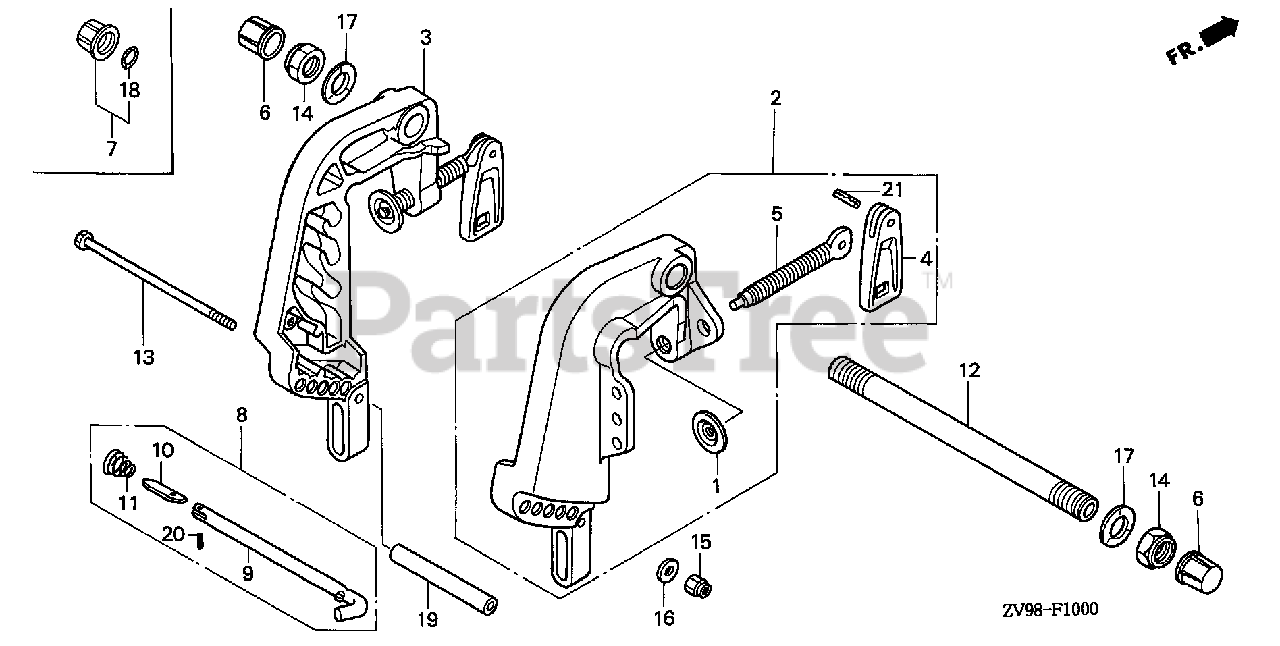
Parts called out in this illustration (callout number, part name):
1	PLATE, PUSH
2	BRACKET, R. STERN *NH282MU* (OYSTER SILVER METALLIC-U)
3	BRACKET, L. STERN *NH282MU* (OYSTER SILVER METALLIC-U)
4	GRIP, CLAMP *NH282MU* (OYSTER SILVER METALLIC-U)
5	SCREW, CLAMP (NOT AVAILABLE)
5	SCREW, CLAMP
6	CAP, TILTING BOLT
8	ROD, ADJUSTING
9	ROD, ADJUSTING
10	STOPPER, ROD
11	SPRING, ADJUSTING ROD
12	SHAFT, TILTING
13	BOLT, HEX. (8X163)
14	NUT, SELF-LOCK (7/8-14UNF)
15	NUT, SELF-LOCK (8MM)
16	WASHER, PLAIN (8MM)
17	WASHER, WAVE (22MM)
18	O-RING (15.54X2.62)
19	COLLAR, DISTANCE (8MM)
20	PIN, SPRING (2.5X8)
21	PIN, SPRING (4X14)
